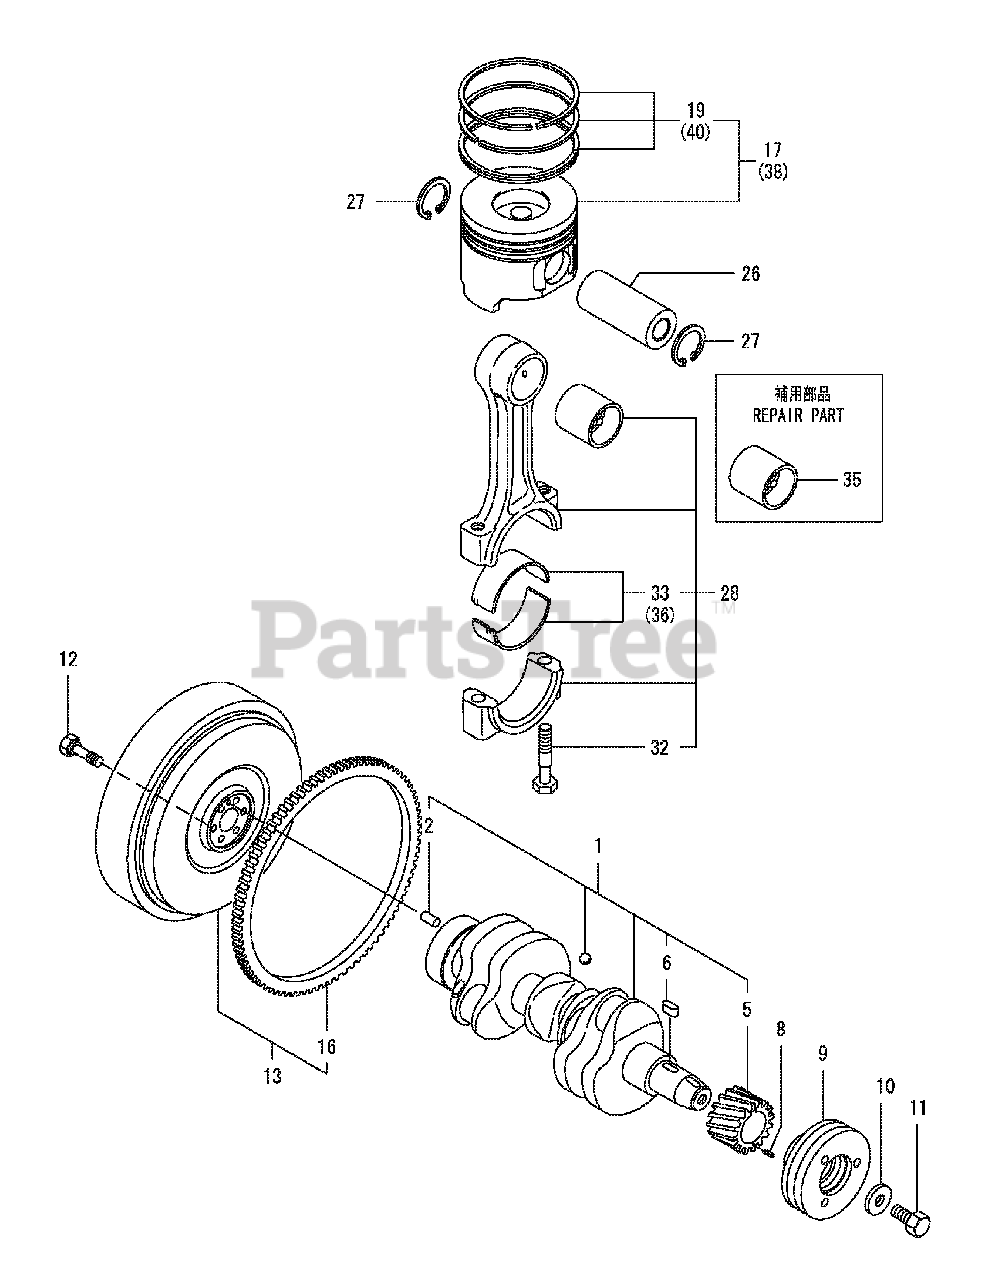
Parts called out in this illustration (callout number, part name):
1	Crankshaft Assembly
2	Parallel Pin, M8 x 16
5	Crankshaft Gear
8	Spring Pin, 3 x 10
9	Crankshaft V-Pulley
13	Flywheel Assembly
17	Piston w/ Ring
19	Piston Ring Set
28	Connecting Rod Assembly
32	Connecting Rod Bolt
33	Crank Pin Metal Assembly
35	Piston Pin Bushing
36	Pin Bearing, 0.25
38	Piston w/ Ring, .25OS
40	Piston Ring Set, .25
